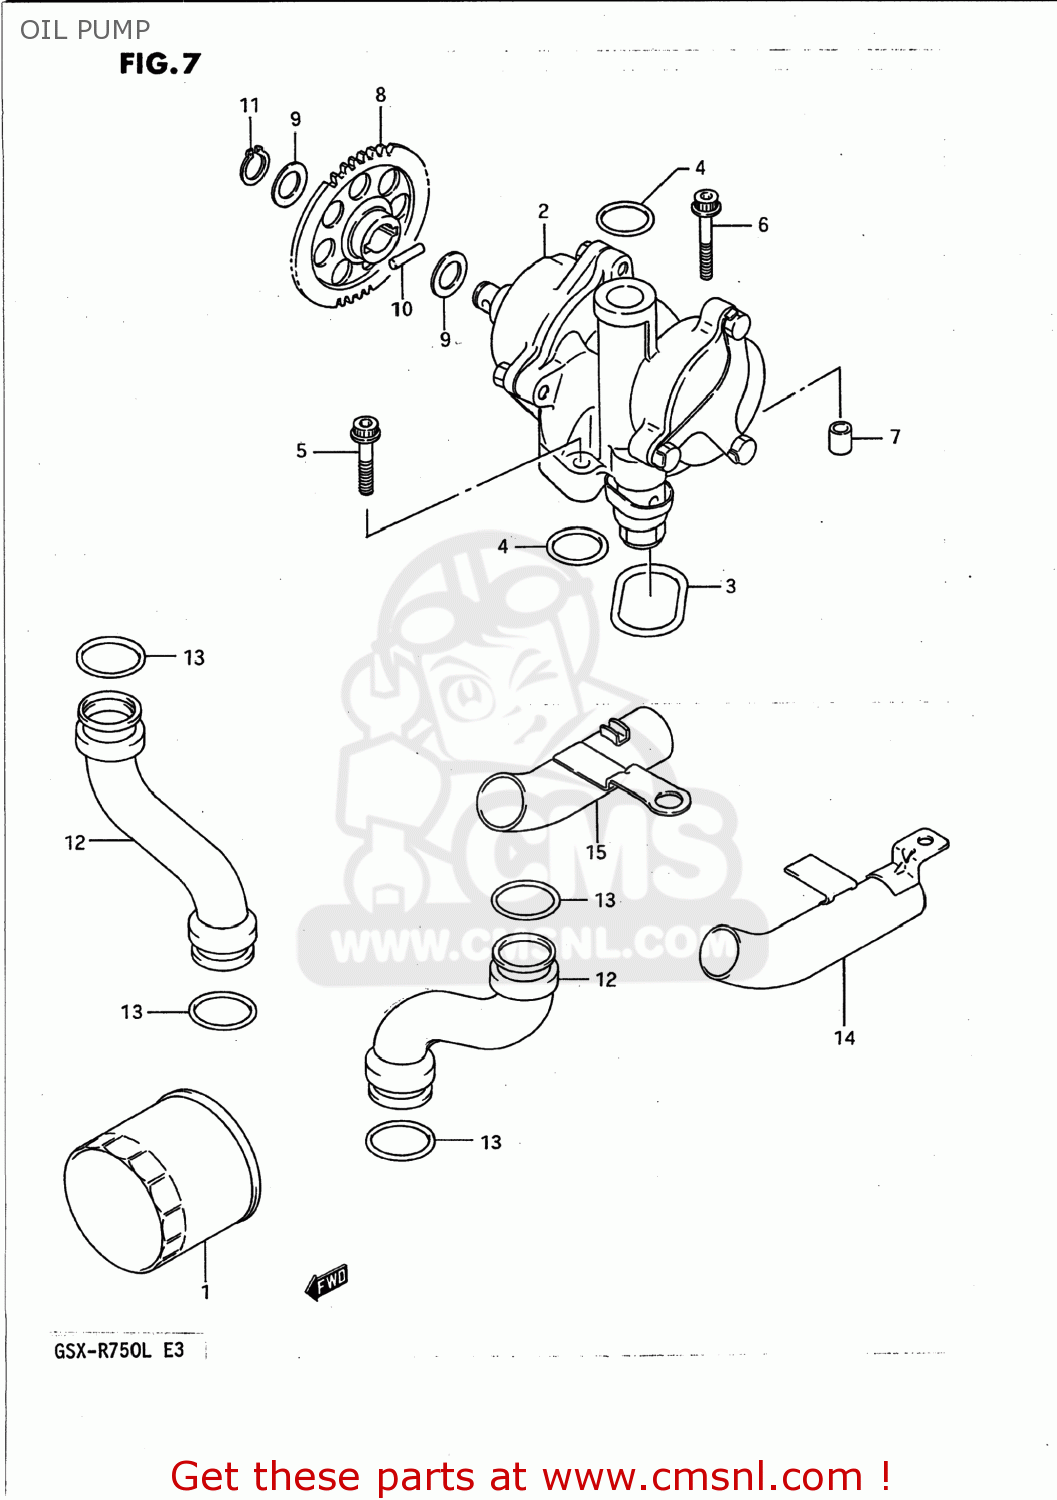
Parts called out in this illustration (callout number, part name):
1	FILTER,OIL
2	PUMP ASSEMBLY,OIL
3	O RING,OIL PUMP
4	O RING(D:3.2,ID:17.8)
5	BOLT
6	BOLT
7	PIN
8	GEAR,OIL PUMP DRIVEN
9	SHIM
10	PIN(5X18)
11	CIRCLIP
12	PIPE,OIL OUTLET
13	O RING(D:3.7,ID:21.7)
14	PIPE,OIL OUTLET UNDER,L
15	PIPE,OIL,OUTLET,UNDER
